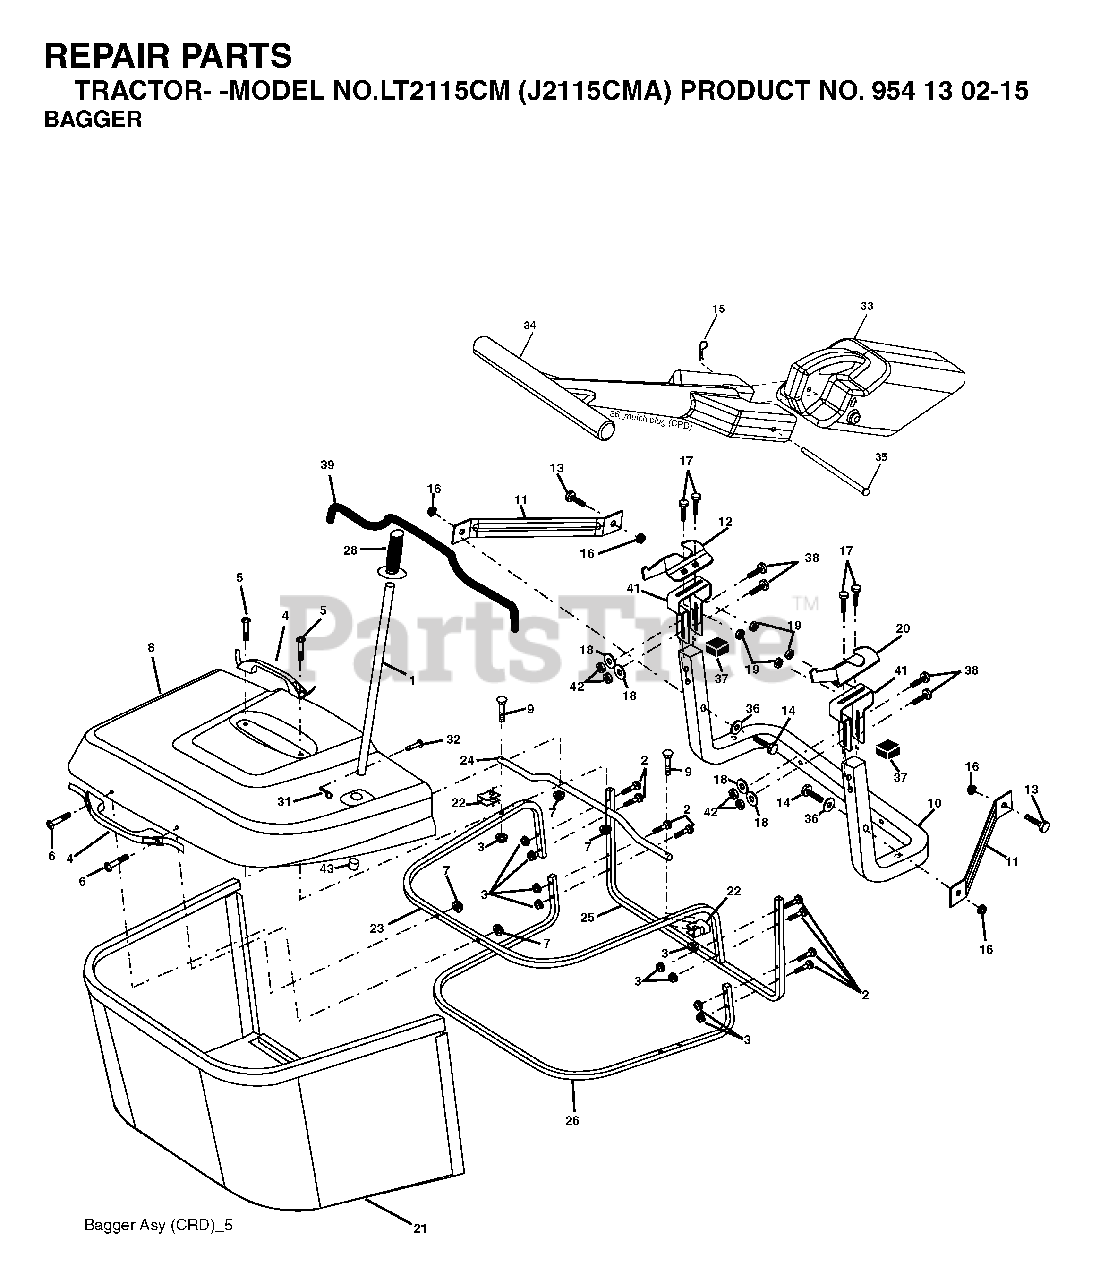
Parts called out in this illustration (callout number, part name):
1	TUBE HANDLE
3	NUT T
5	SCREW.PAN.HEAD
11	BRACKET
14	BOLT-HEX EAK
15	RETAINER-SPRNG RB
16	NUT LOCK FLG 3/8-16 UNC
17	BOLT
18	WASHER M
19	NUT LOCK HEX FLANGE 5/16-18
20	BRACKET
21	GRASS BAG
22	BRACKET
23	TUBE
24	TUBE
26	TUBE
28	GRIP.HANDLE.BLACK
31	RETAINER CLIP
32	RIVET,DRILLED
33	PLUG
35	PIN
36	WASHER
38	BOLT.5/16-18X2.5
41	BRKT, BAGGER
42	NUT.71038.31-18.HEX.NYLOCK
43	PLUG, TUBING END
